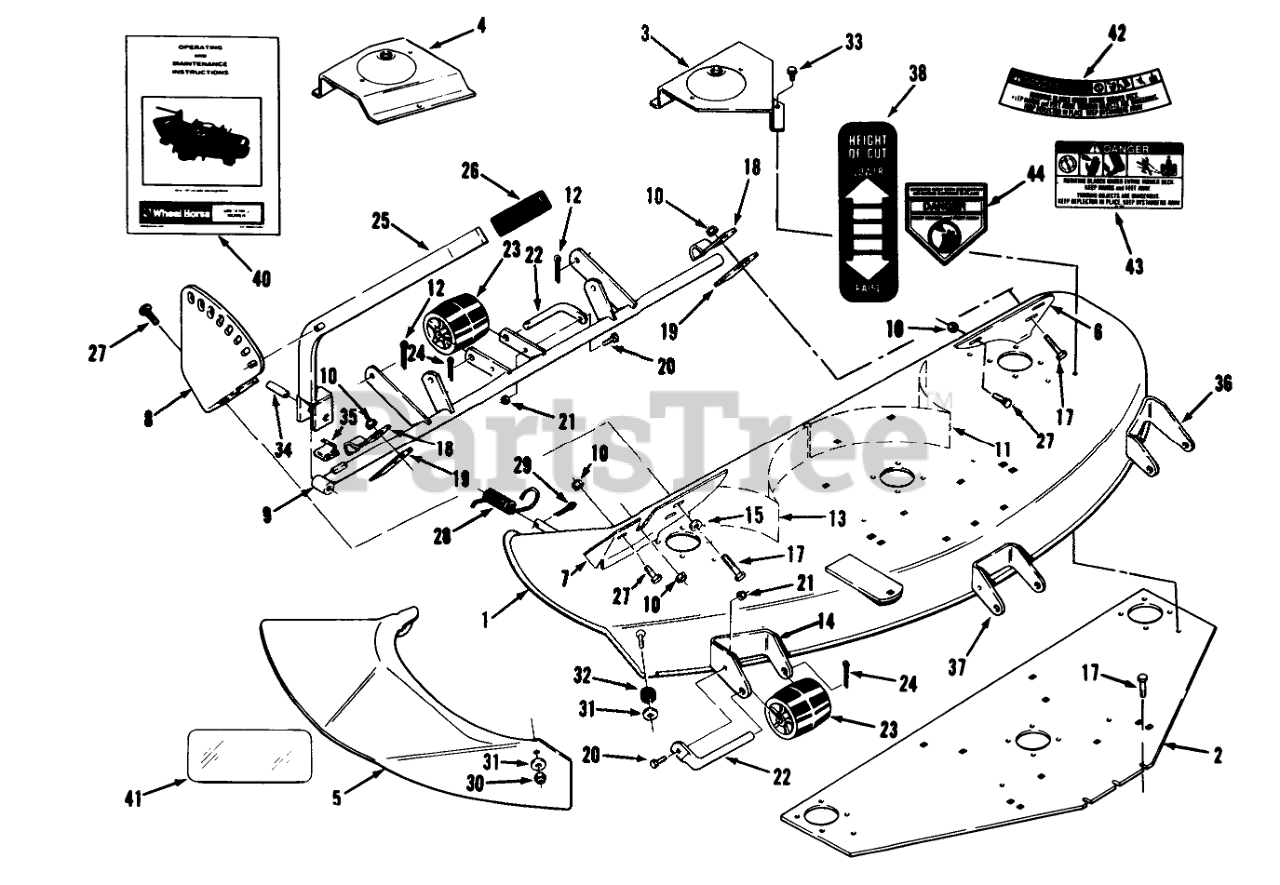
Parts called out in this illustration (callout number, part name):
1	Deck-Mower (Incl. Ref. #2, 6, 7, 11, 14, 36 & 37)
2	Plate-Deck
3	Belt Cover LH
4	Belt Cover RH
5	Chute Extension
6	PLATE-WEAR L.H. R
7	PLATE-WEAR R.H. R
8	Quadrant
9	Support-Lift
10	NUT
11	BAFFLE-DECK LH
12	Hairpin
13	BAFFLE-DECK RH
14	BRKT-ROLLER R
15	Washer
17	Bolt
18	Clamp
19	Bar
20	Bolt
21	Nut
22	ROLLER-SHAFT
23	Roller
24	Cotter Pin
25	Lever
27	Bolt
28	Spring
29	Pop Rivet
30	Nut
31	Washer
32	BUSHING-PIVOT
33	Bolt
34	SPIROL PIN 3/8X1 1/2
35	CLIP-SPRING
36	BRKT-ROLER R
37	BRKT-ROLLER
38	DECAL-HOC
40	Manual-Operator-s
41	DECAL-OVERLAY
42	DECAL - DANGER
43	DECAL-DANGER, THROWN OBJECT
44	DECAL-DANGER
